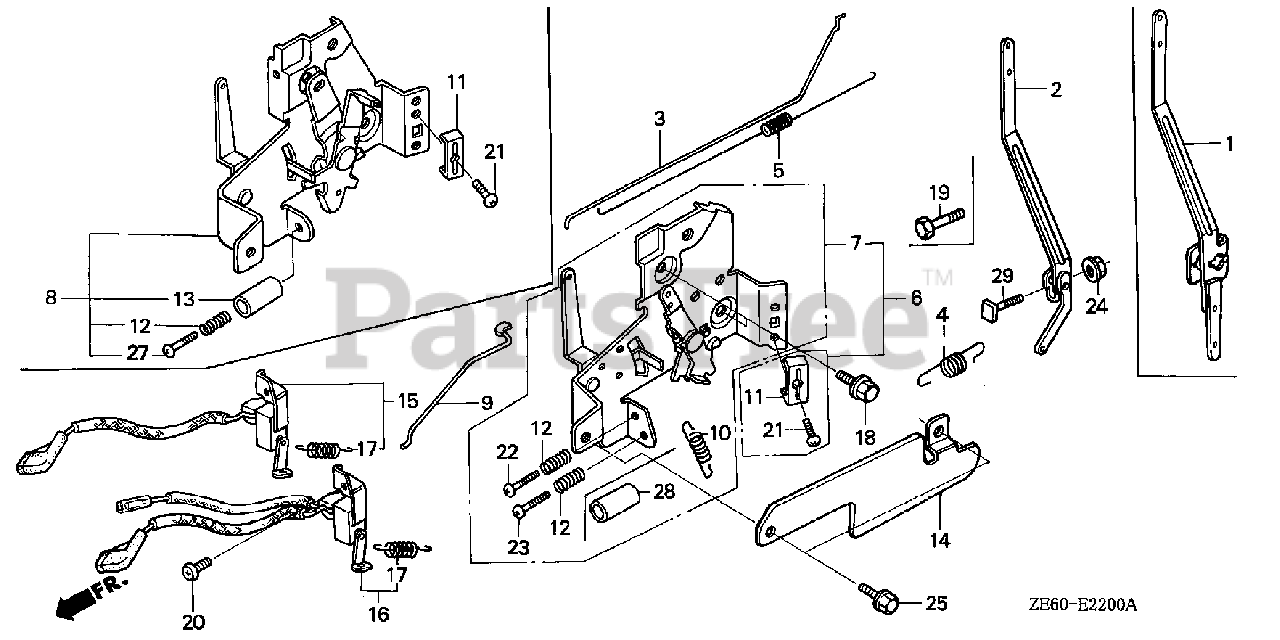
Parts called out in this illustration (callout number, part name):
1	ARM, GOVERNOR (C,G)
3	ROD, GOVERNOR
4	SPRING, GOVERNOR
5	SPRING, THROTTLE RETURN
6	CONTROL
8	CONTROL
9	ROD, CHOKE
11	HOLDER, CABLE
12	SPRING, CONTROL ADJUSTING
16	SWITCH ASSY., ENGINE STOP
17	SPRING, SWITCH CONTROL
18	BOLT, FLANGE (6X12) (CT200)
18	BOLT, FLANGE (6X14) (CT200)
20	SCREW, PAN (4X8)
21	SCREW, PAN (5X16)
22	SCREW, PAN (5X20)
23	SCREW, PAN (5X25)
24	NUT, FLANGE (6MM)
27	SCREW, PAN (5X25)
29	BOLT, GOVERNOR ARM
